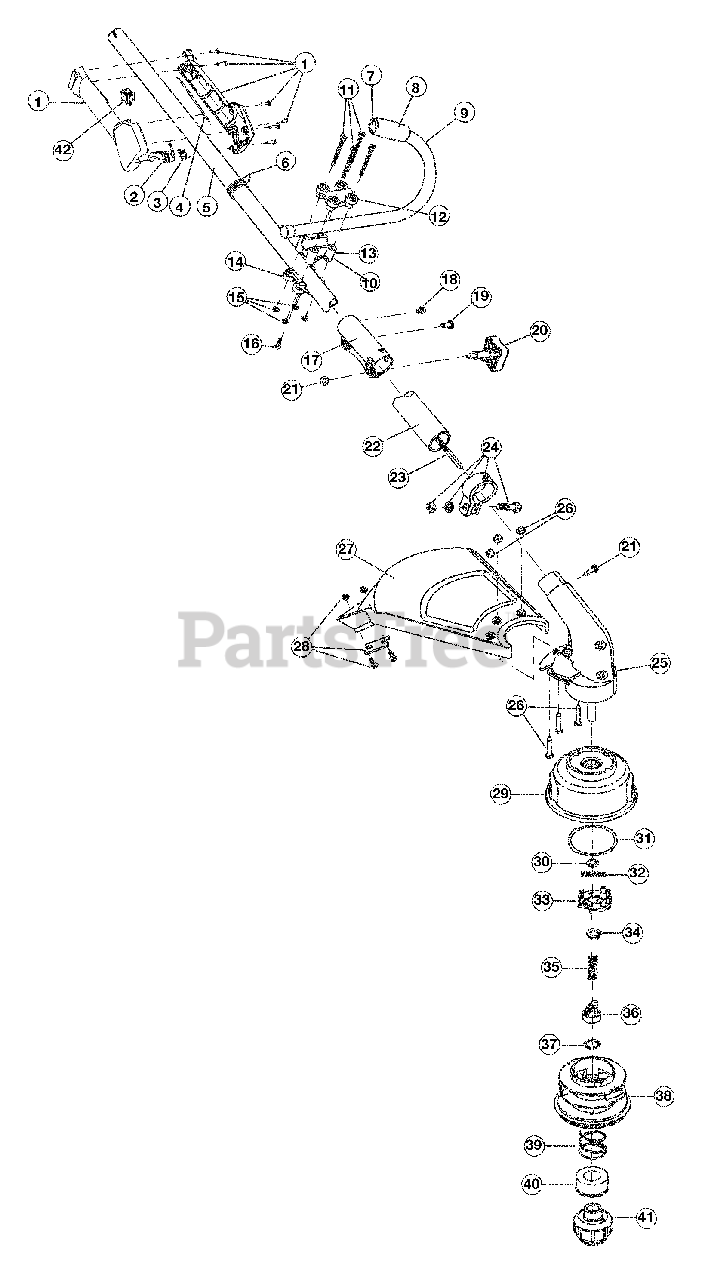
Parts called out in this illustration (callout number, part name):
1	Throttle Housing & Trigger Assembly
2	Throttle Trigger Spring
3	Throttle Trigger
4	Throttle Cable Assembly
5	Upper Drive Shaft Housing Assembly
6	Harness Clip
7	Tube Closure
9	J-Handle Assembly
10	Handle Bracket Assembly
12	Upper Handle Clamp
13	Middle Handle Clamp
14	Lower Handle Clamp
16	Anti-Rotation Screw
17	Split Boom Coupler
20	Adjustment Knob
21	Knob Retaining Nut
22	Lower Drive Shaft Housing Assembly
23	Lower Flexible Drive Shaft
24	Lower Clamp Assembly
25	Gearbox Assembly
26	Shield Mounting Hardware
27	Shield Assembly
28	Blade Assembly
29	Outer Spool Assembly
30	Retainer
31	Thrust Washer
32	Small Spring
33	Slider
36	Plunger
38	Inner Reel
39	Large Spring
40	Foam Seal
41	Bump Knob Assembly
